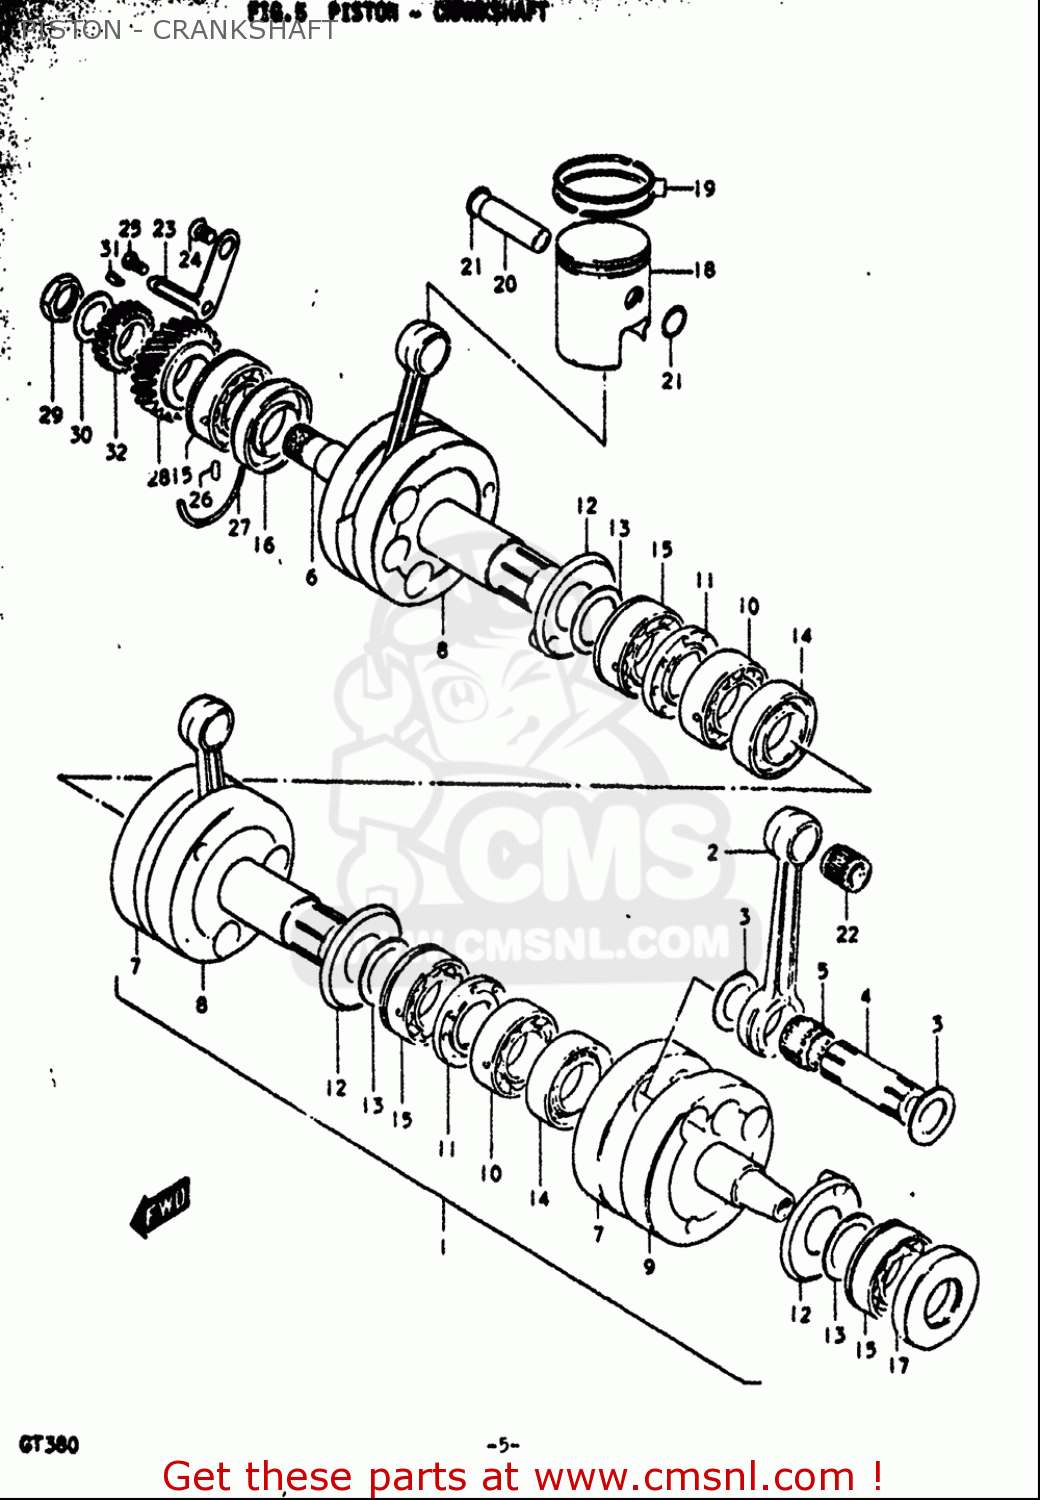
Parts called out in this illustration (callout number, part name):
2	CONNECTING ROD
3	WASHER (20X34X1)
5	BEARING(20X26X16.7)
10	BEARING(25X52X15)
12	PLATE,CSHAFT OIL GUIDE
13	SHIM(25X36X0.5)
14	SEAL,OIL(25X52X11)
15	BEARING 25X52X15
17	SEAL,OIL(25X52X8.5)
18	PISTON SET(OS:0.5)
19	RING SET,PISTON
20	PIN,PISTON 14MM
21	RING,SNAP 14MM
22	BEARING(14X18X19.8)
24	SCREW
25	SCREW
26	PIN
27	C RING
29	NUT
30	WASHER
31	KEY
